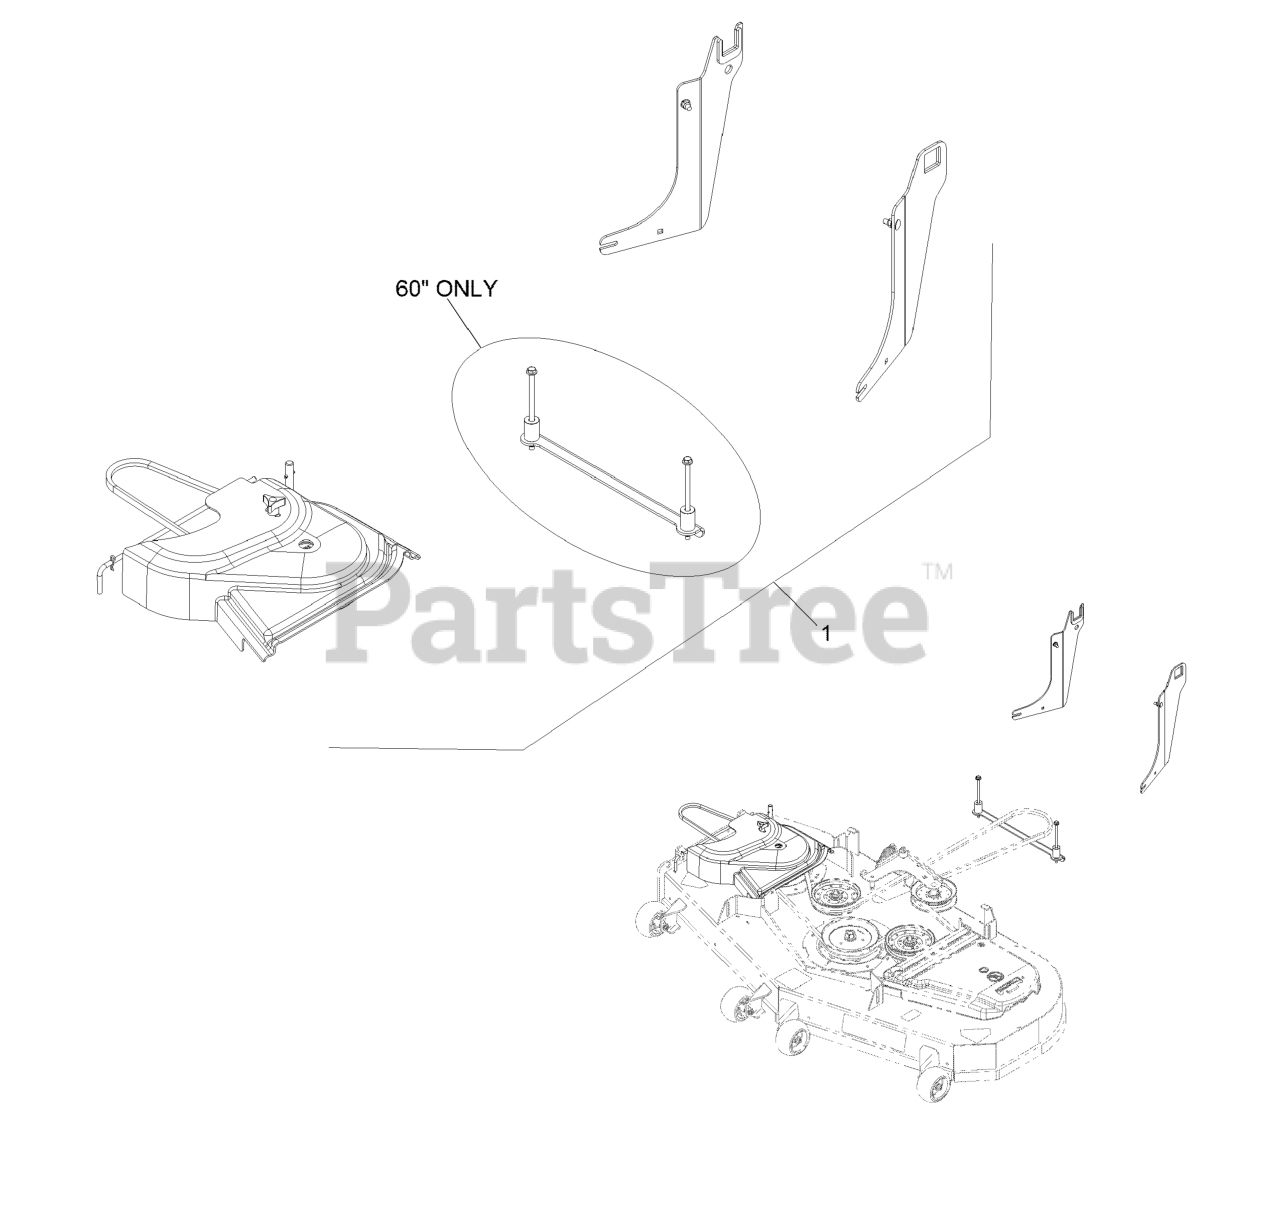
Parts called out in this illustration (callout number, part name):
1	Kit-Completing Qsp 44 Uve
1	Kit-Completing Qsp 48 Uve
1	Kit-Completing Qsp 52 Uve
1	Kit-Completing Pi 44 Uve
1	Kit-Completing Pi 48 Uve
1	Kit-Completing Pi 52 Uve
1	Kit-Completing Pn60 Uve
